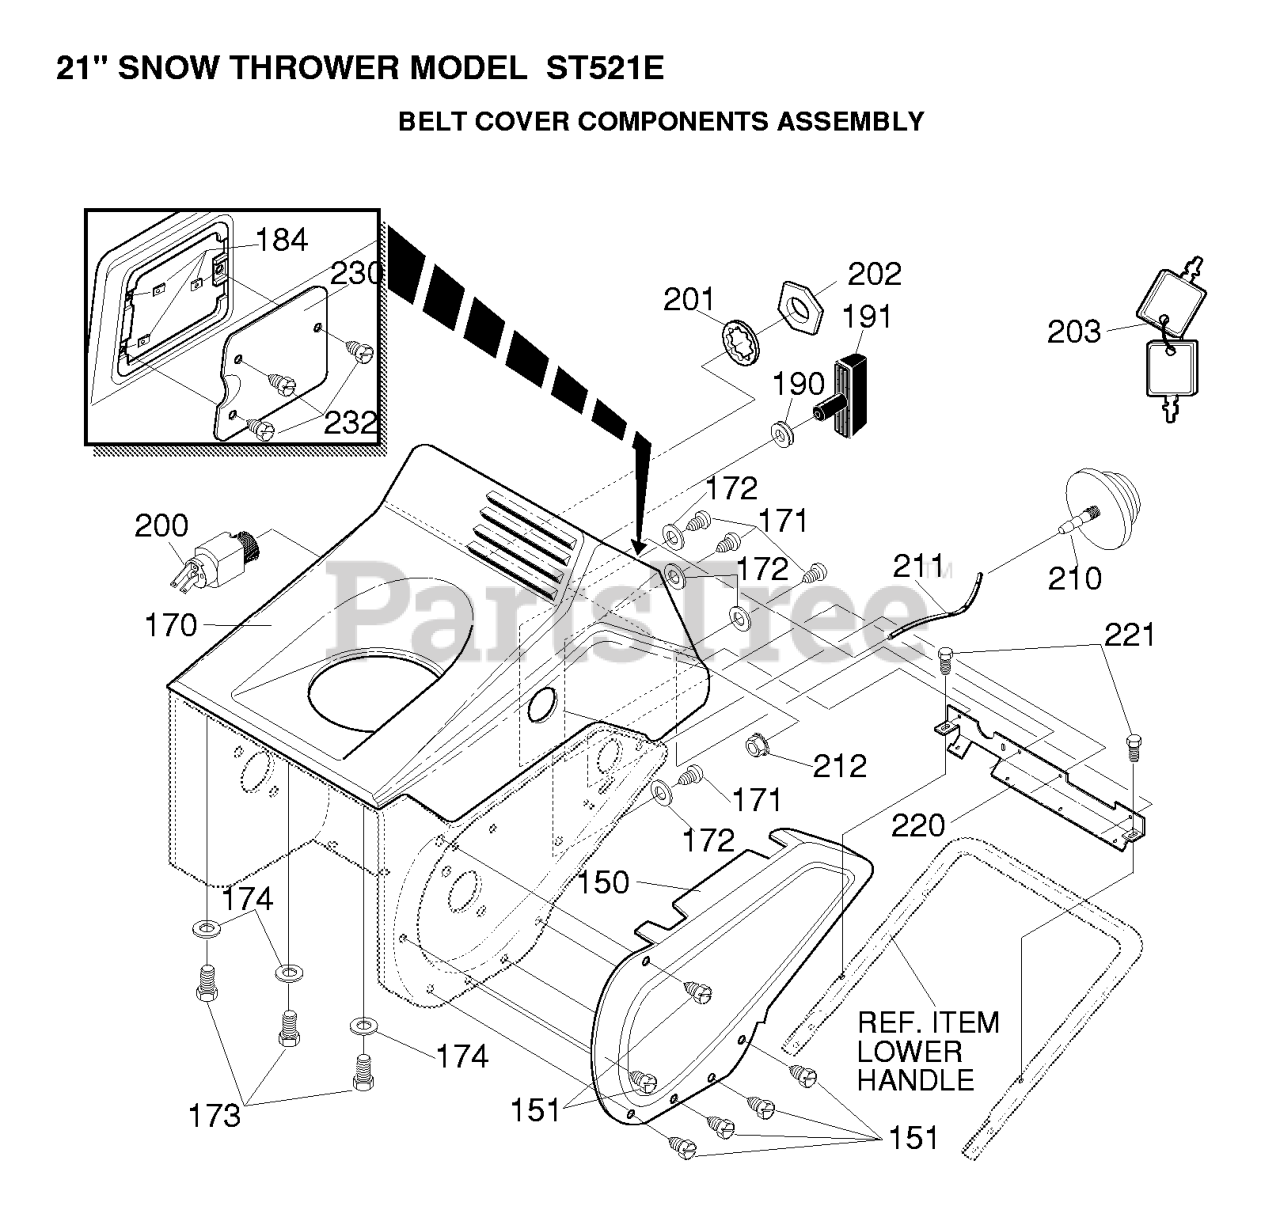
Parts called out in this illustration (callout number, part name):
150	COVER, BELT 2CY
151	SCREW, 10-24X.38 SLHWATAP
170	COVER, TOP
171	SCREW, #10-24X.63 TRPHTAP
173	SCREW, #10-14 X .63
174	WASHER, FLAT .250X .56X.
184	NUT, TINN "U" TYPE
190	GROMMET & WASHER
191	KNOB, PLASTIC
203	2 KEYS & RING
211	HOSE,PRIMER 5.75 TEC
212	NUT, 1/4-20 HEX KEPS
220	BRACKET, SHROUD MNTG
221	SCREW, #10-24 X .63 TRPHTAP
230	DOOR, ACCESS
232	SCREW #10-16 X .75
